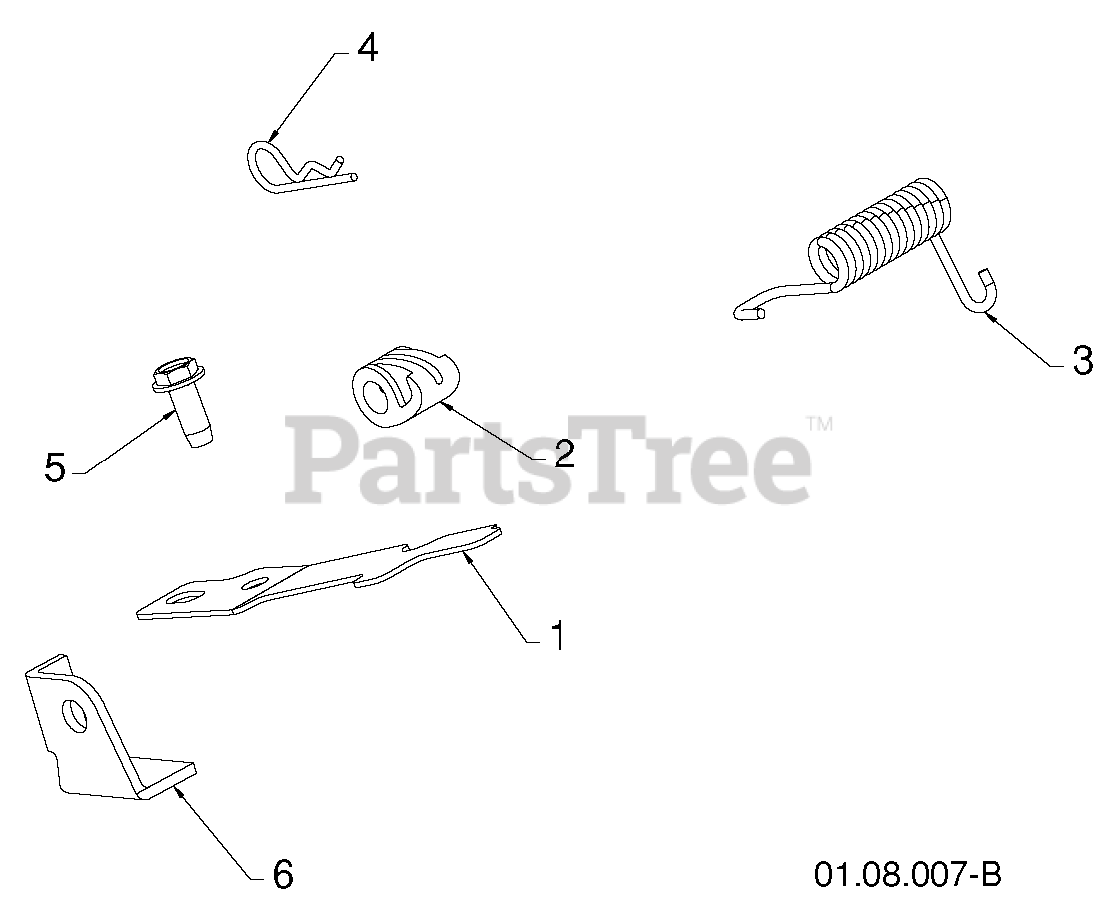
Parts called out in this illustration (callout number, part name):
1	SPRING.INTERLOCK
2	CAM.INTERLOCK.RELEASE
3	RP SPRING, TORSION
4	SPRING RETAINER
5	SCREW 14-20 X 5/8
6	STOP.INTERTLOCK
